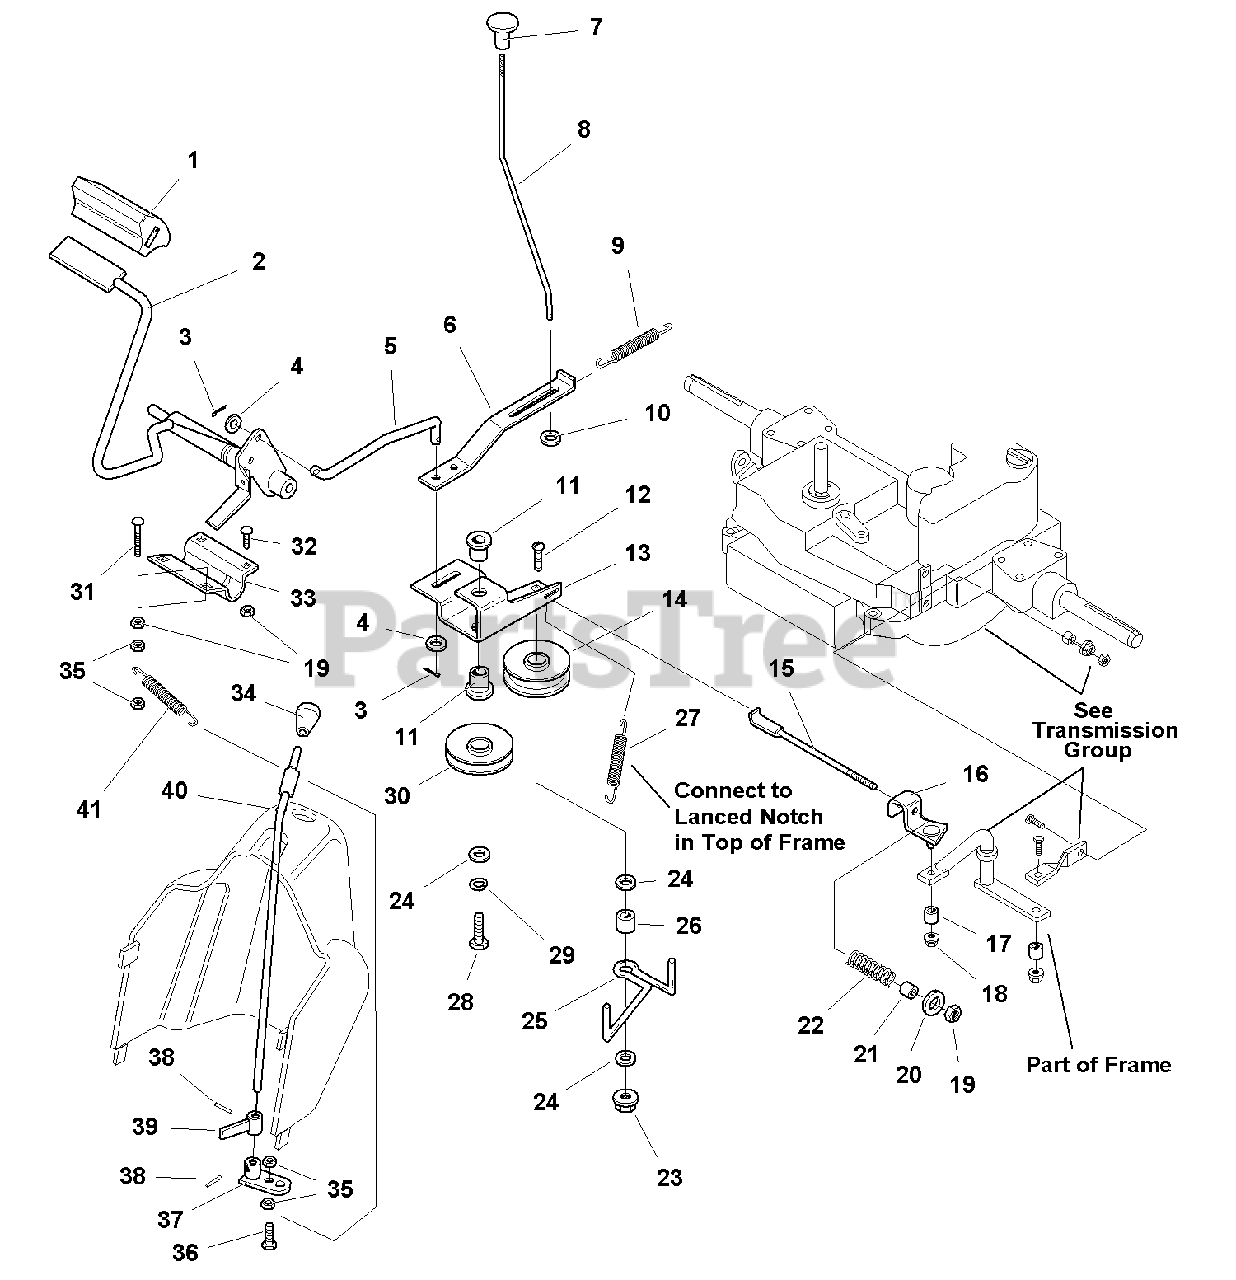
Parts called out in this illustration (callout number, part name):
1	PAD, Brake Black Rubber
2	FOOT PEDAL & BRAKE ARM ASSEMBLY
3	PIN, Cotter, 1/8 X 3/4
6	LEVER, Parking
9	SPRING, Extension
10	WASHER
12	CARRIAGE BOLT, 3/8-16 x 2-1/4
14	PULLEY, Idler
16	GUIDE BELT & STUD ASSEMBLY
18	NUT, Hex Flange, 5/16-18
19	NUT, Hex Lock, 5/16-18
20	WASHER
22	SPRING, Compression
23	NUT, Hex Head Whiz Lock, 3/8-16
24	WASHER
27	SPRING, Extension
28	CAPSCREW, Hex Head, 3/8-16 x 1-3/4
29	LOCKWASHER, 3/8
31	CARRIAGE BOLT, 5/16-18 x 1-1/2
32	CARRIAGE BOLT, 5/16-18 x 3/4
35	NUT, 5/16-18
36	CAPSCREW, Hex Head, 5/16-18 x 1
37	ARM & HUB ASSEMBLY
38	PIN, SPRING
39	HUB & BAR ASSEMBLY
40	SHAFT, Control
41	SPRING, Extension
